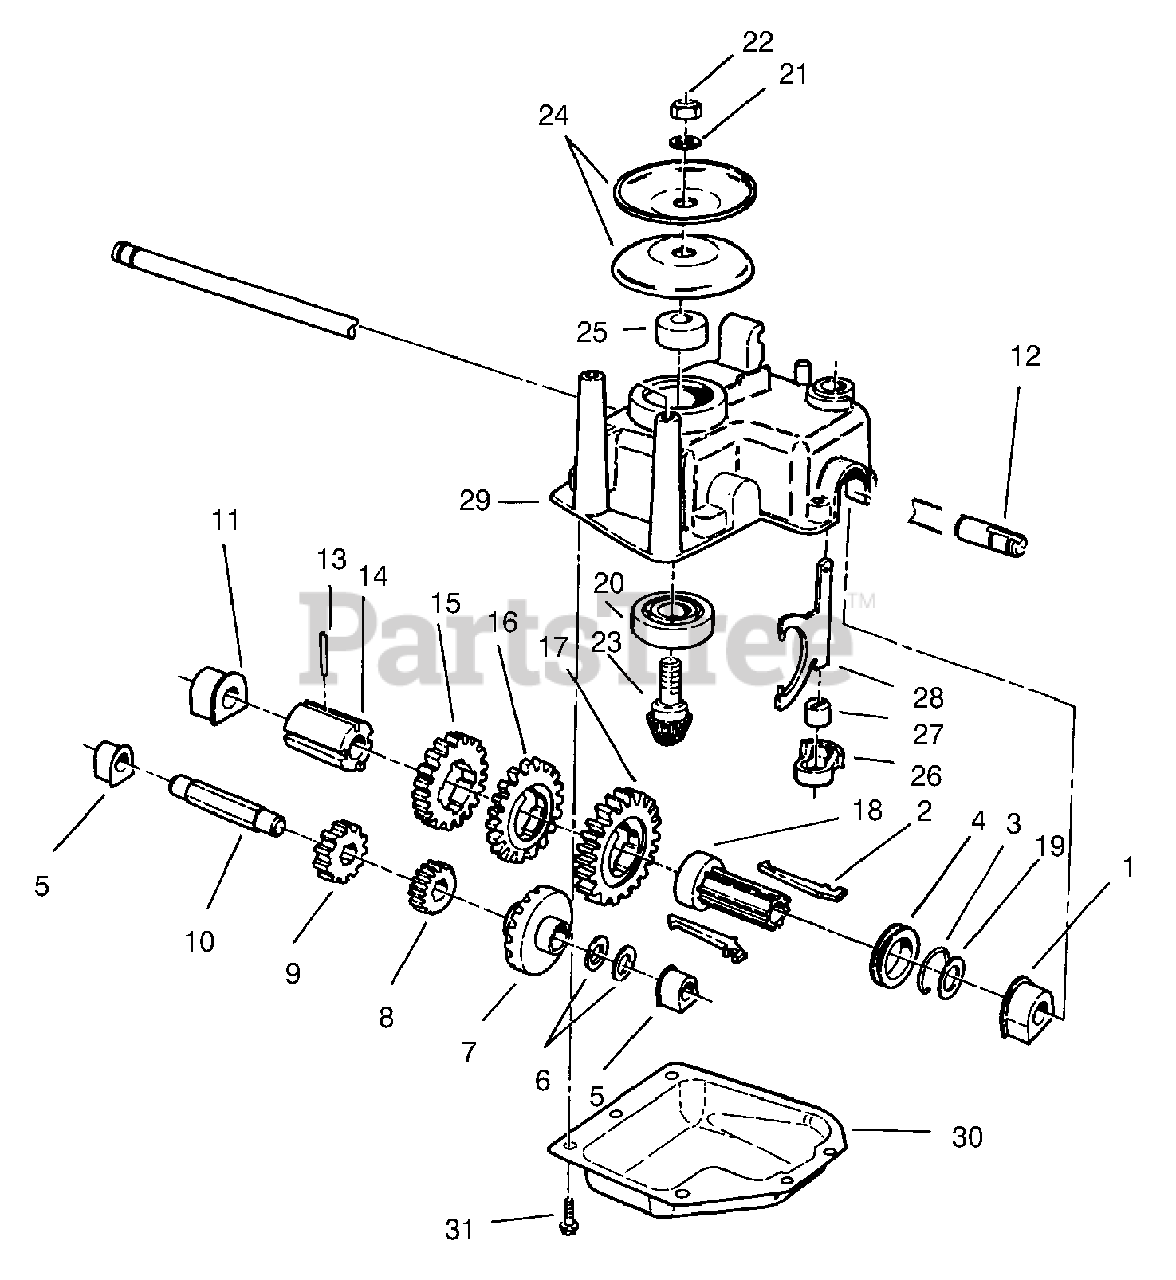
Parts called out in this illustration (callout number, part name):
1	Bushing-Output
2	Key-Shift
3	Clip-Spring
4	Collar-Shift
6	Washer-Thrust
7	Gear-Bevel
8	20 T Pinion
9	25 T Pinion
10	Shaft-Intermediate
11	Bushing-Output
12	Shaft-Output
13	Pin-Groove
14	Sleeve-Gear
15	39 T Gear
16	44 T Gear
17	49 T Gear
18	Sleeve-Key, Shift
20	Bearing-Ball
21	Washer-Flat
22	Nut-Lock, NI
24	Pulley-Half
26	Retainer-Shift Fork
27	Bushing-Yoke
28	Yoke-Shift
29	Case-Gear, Upper
30	Cover-Gear Case
31	Screw-Taptite
